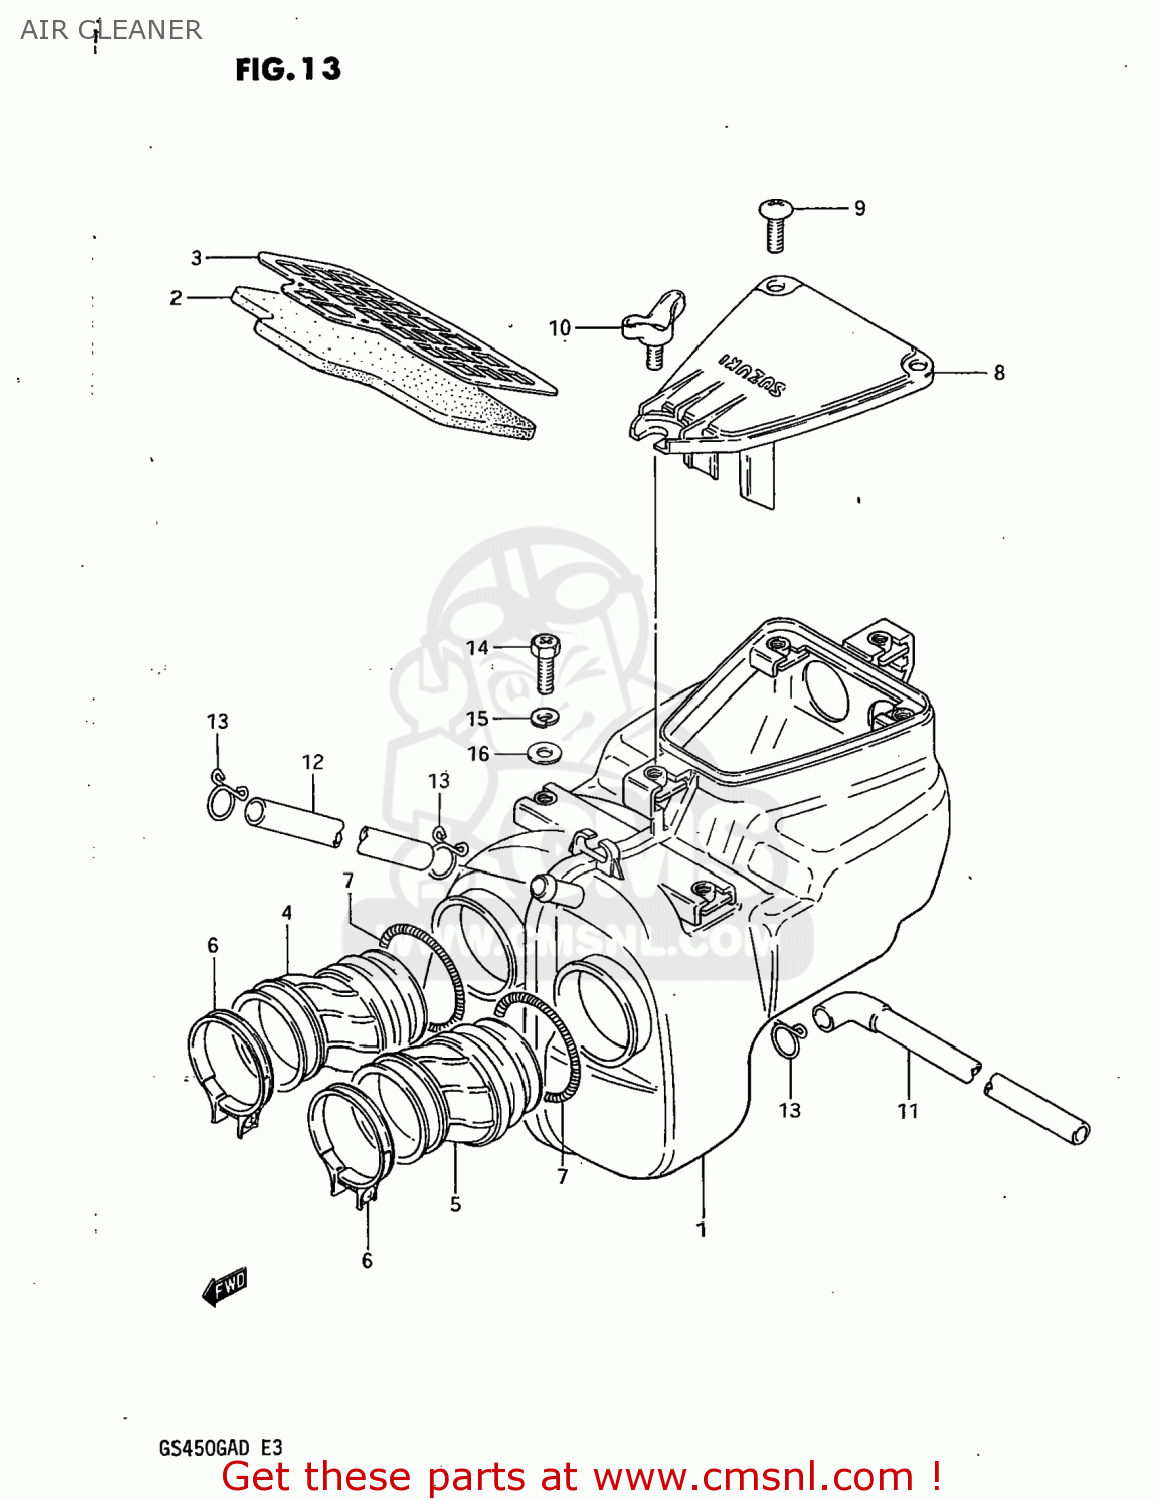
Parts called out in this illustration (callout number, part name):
1	CLEANER ASSEMBLY,AIR
2	FILTER
3	HOLDER,OUTER
4	TUBE,OUTLET,R
5	TUBE,OUTLET,L
6	CLAMP
7	CLAMP,CLEANER SIDE
8	CAP,AIR CLEANER
9	SCREW
10	BOLT, WING
11	DRAIN TUBE
12	TUBE,BREATHER
13	CLAMP
14	BOLT L:16
15	LOCK WASHER
16	WASHER
